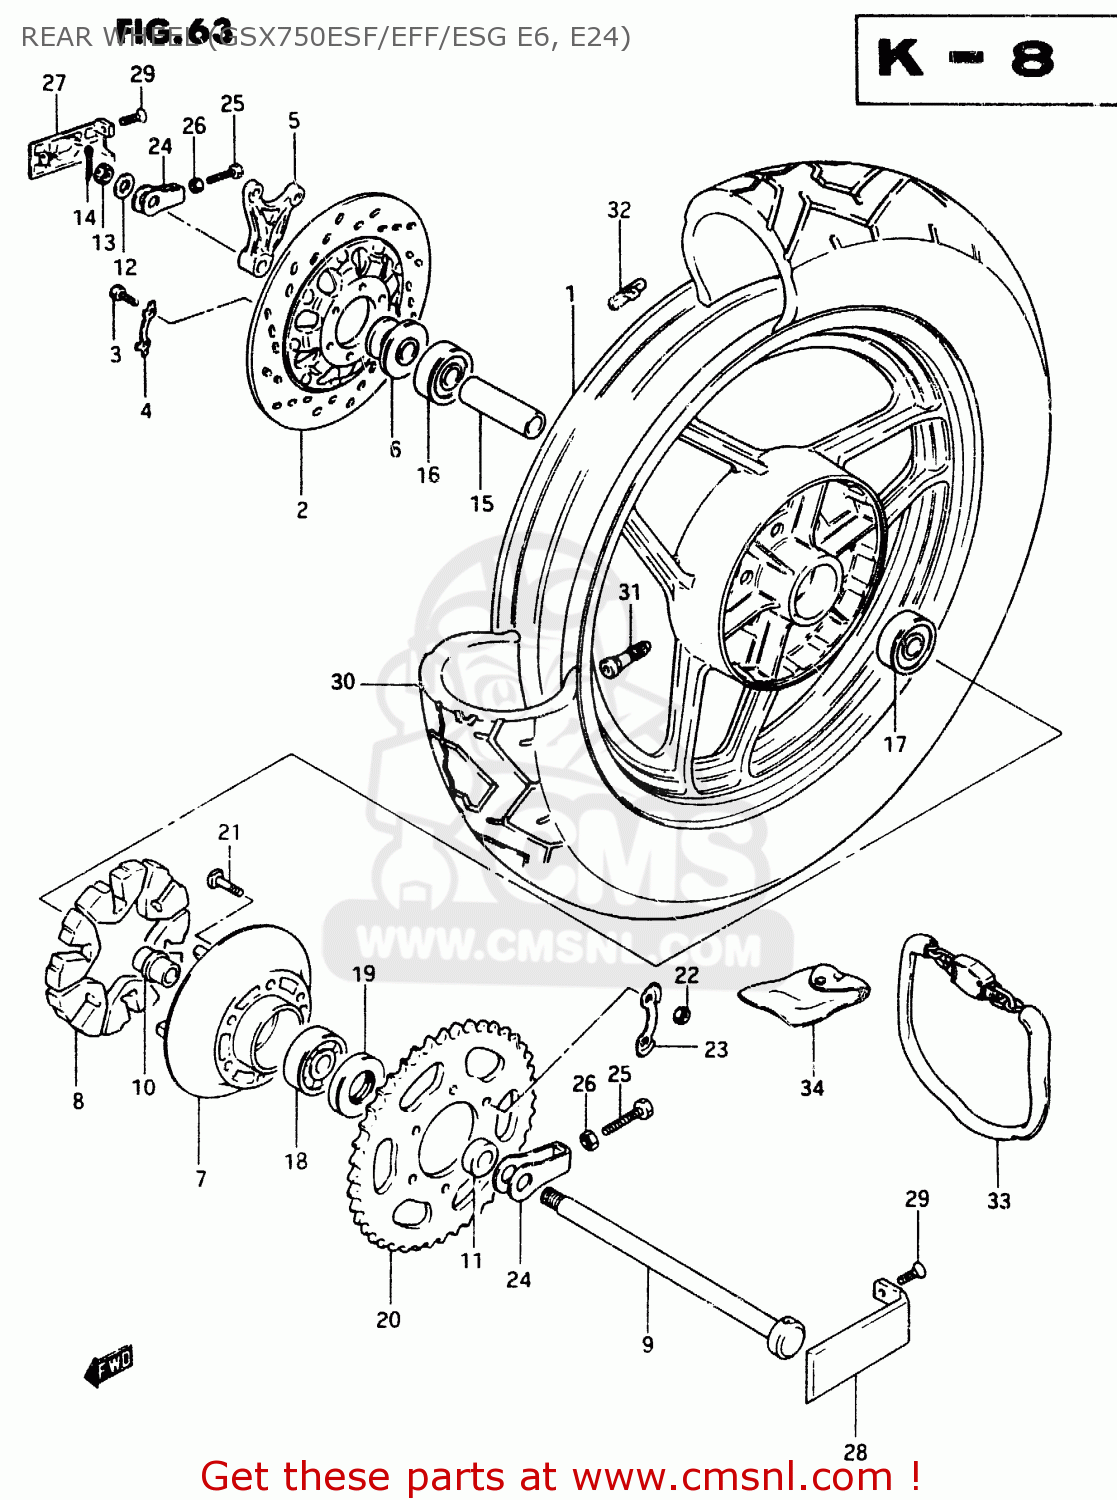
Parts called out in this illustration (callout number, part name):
1	WHEEL, REAR (MT3.00X18)(GOLD)
2	DISC,BRAKE
3	BOLT(8X30)
4	WASHER
5	BRACKET,REAR CALIPER
6	SPACER,REAR AXLE,RIGHT
7	DRUM,REAR SPROCKET MOUNT
8	ABSORBER,REAR HUB SHOCK
9	AXLE,REAR
10	RETAINER,RR SPROCKET DRUM
11	SPACER(17X33X11.3)
12	WASHER
13	NUT
14	PIN,COTTER
15	SPACER(17.5X25X88)
16	BEARING
17	BEARING
18	BEARING
19	SEAL,OIL(33X62X7)
20	SPROCKET,REAR (NT:45)
21	BOLT(10X35.5)
22	NUT
23	WASHER
24	ADJUSTER,CHAIN
25	BOLT
26	NUT
27	COVER,CHAIN ADJUSTER,R
28	COVER,REAR AXLE,LEFT
29	SCREW 5X16
30	TIRE, REAR (130/80V18)
31	VALVE,TIRE
32	BALANCER,WHEEL
33	CHAIN LOCK ASSY
34	BAG,CHAIN LOCK
